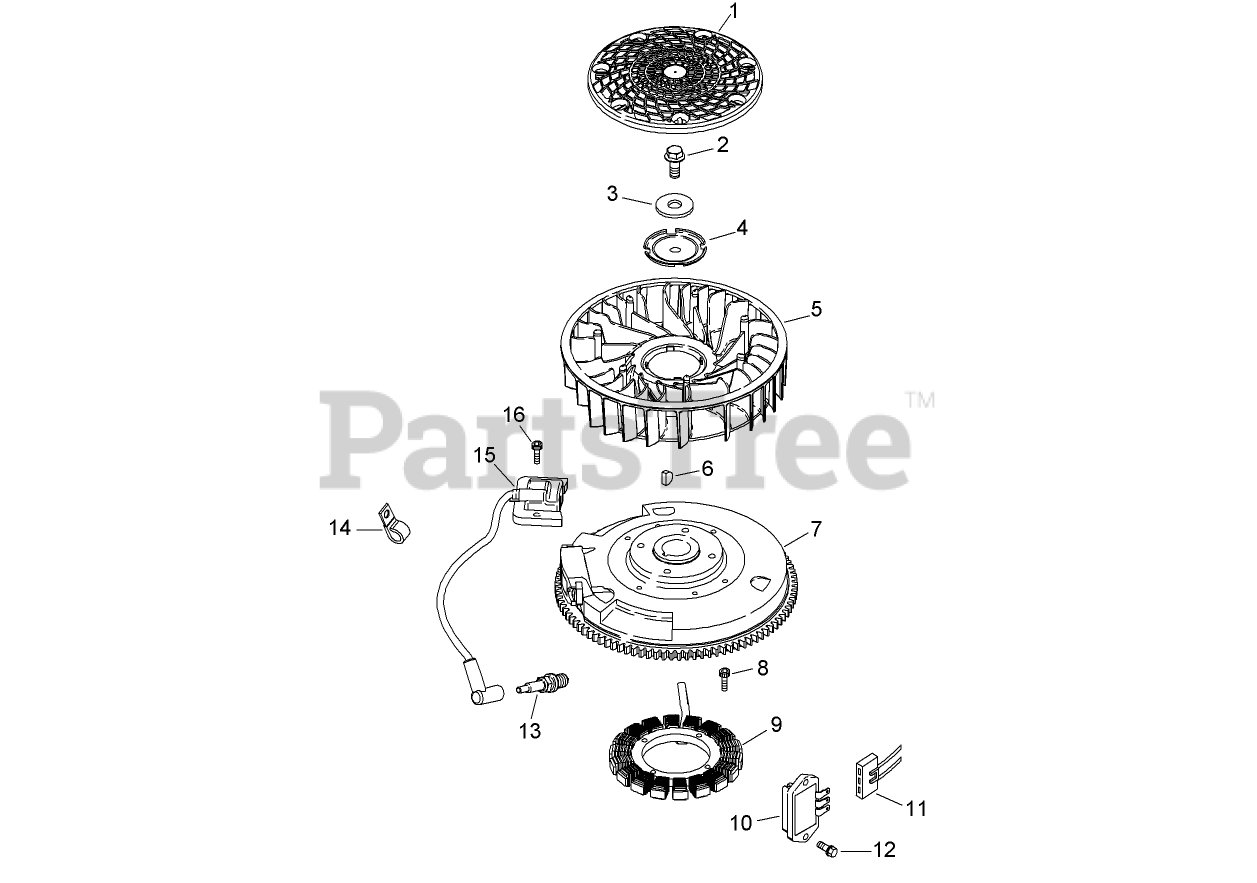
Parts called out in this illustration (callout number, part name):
1	Screen-Grass
2	SCREW-FLANGE, HEX
3	WASHER-FLAT
4	PLATE-MOUNTING, FAN
5	Fan
6	KEY (3/16 X 5/8)
7	FLYWHEEL ASM
8	SCREW-DRIVE, TRX HD
9	Kit, Stator (Incl. Terminal 25 452 01-S)
10	RECTIFIER/REGULATOR
11	Connector (3 contact)
12	SCREW-FLANGE, THREAD FORMING (M5X.8X20)
13	SPARK PLUG (R F I)
14	CLIP-CABLE
15	MODULE-IGNITION (C D I FIXED)
16	Screw-Socket, Hex (M5x0.8x25)
